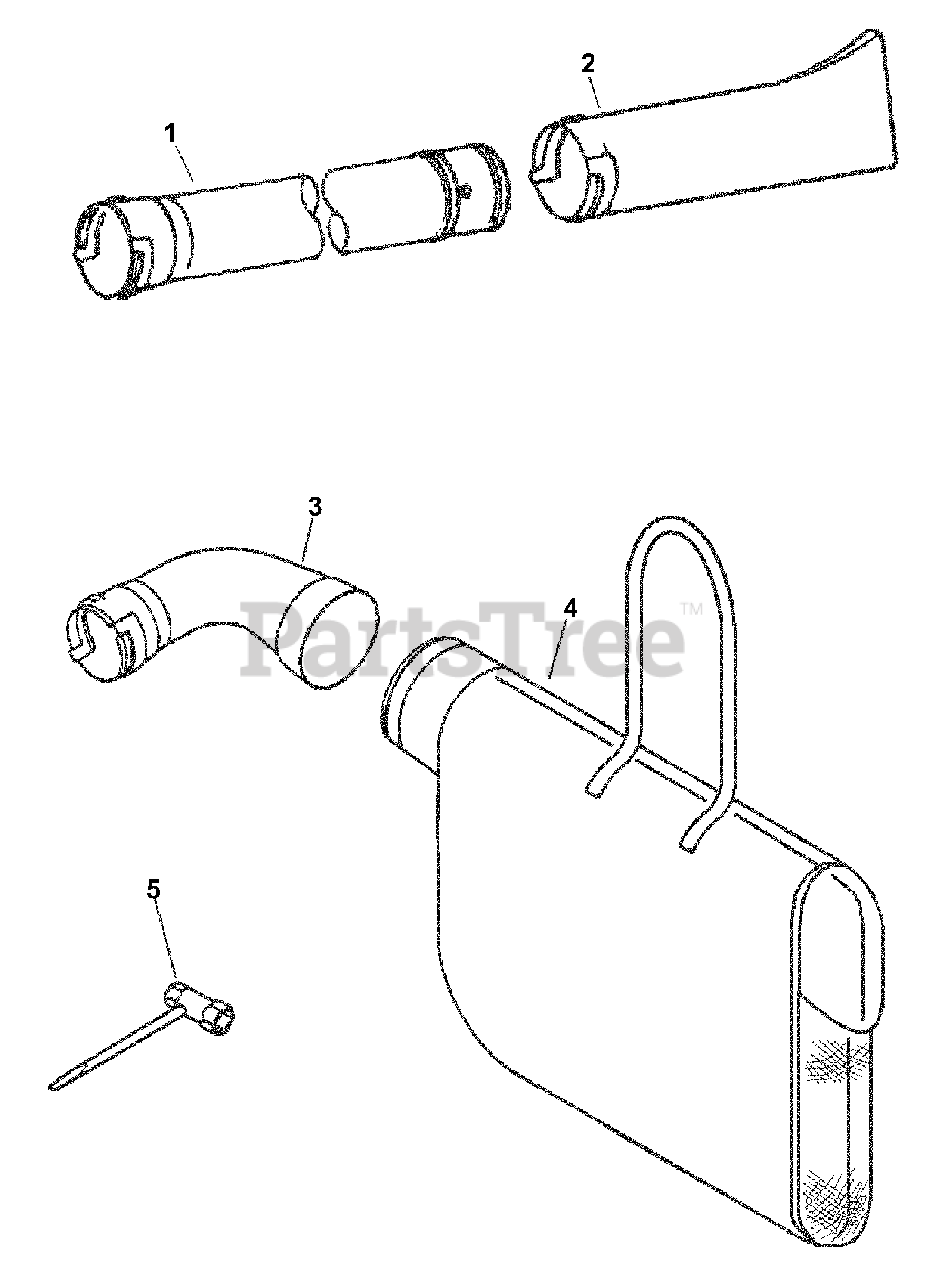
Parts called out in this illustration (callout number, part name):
1	TUBE, BLOWER - STRAIGHT
2	TUBE, BLOWER - NOZZLE
4	BAG, DUST
5	T-WRENCH 13×19×180
